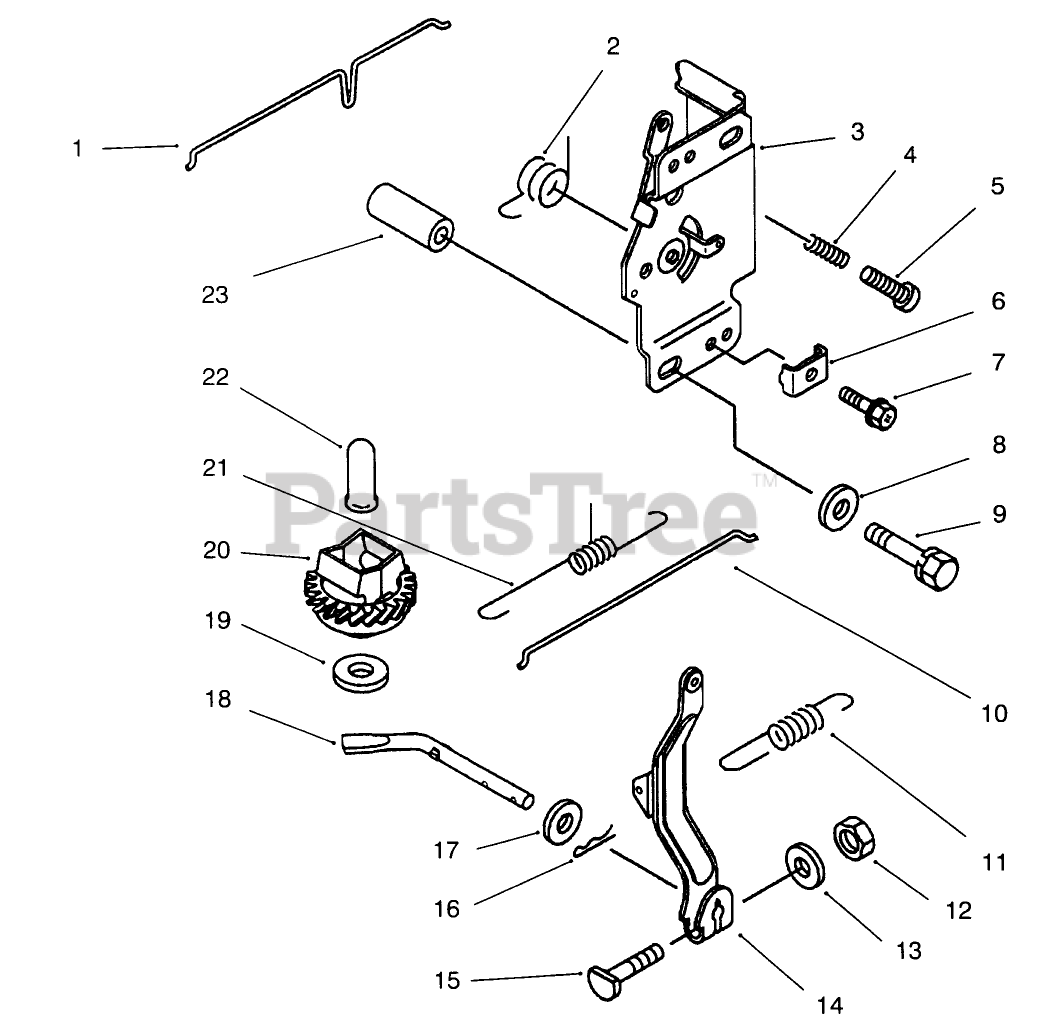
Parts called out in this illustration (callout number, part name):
1	Link-Choke
2	Spring
3	Panel-Comp. Control (Incl. Ref. #2, & 4-7)
4	Spring
5	Screw
6	Clamp
7	BOLT (5X18)
8	Washer
9	Bolt
10	Link
11	Spring
12	NUT-HEX (6mm)
13	Washer-Plain (6mm)
14	Arm ASM
15	Bolt (6X28)
16	Pin-Snap (1.2 X 21.2)
17	WASHER (6.5X11.5X2.0)
18	Arm-Pivot
19	Washer (6.2X20X0.5)
20	Governor ASM
21	Spring
22	Sleeve
23	Collar
